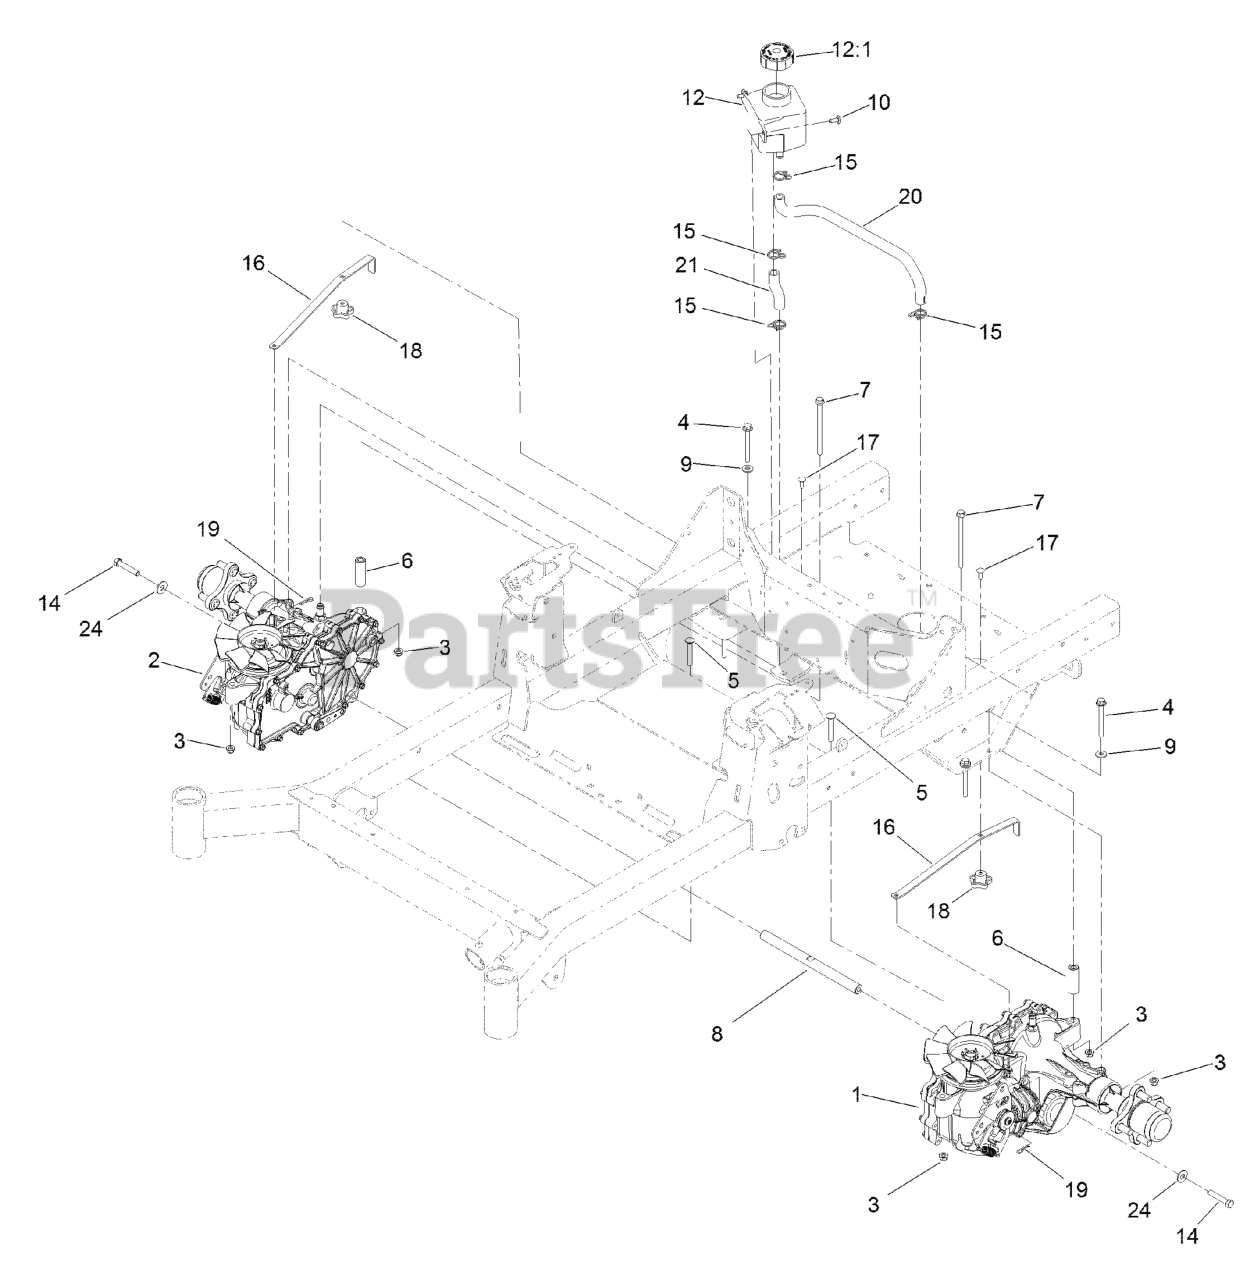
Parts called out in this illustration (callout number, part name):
1	LH TRANSAXLE ASM
2	RH TRANSAXLE ASM
3	NUT-HF, NI
4	SCREW-HHF
5	BOLT-CARR
6	SPACER-HYDRO
7	SCREW HHF
8	SHAFT-SPACER
9	WASHER-SPRING
10	SCREW-TORX
12	TANK-HYD
12:1	CAP-RESERVOIR, HYD
14	SCREW-HH W/LOCTITE
15	CLAMP-HOSE
16	ARM-BYPASS, HYDRO
17	BOLT-CARR
18	KNOB-HANDLE
19	PIN-COTTER
20	HOSE-HYDRAULIC
21	HOSE-HYDRAULIC
24	WASHER-FLAT
